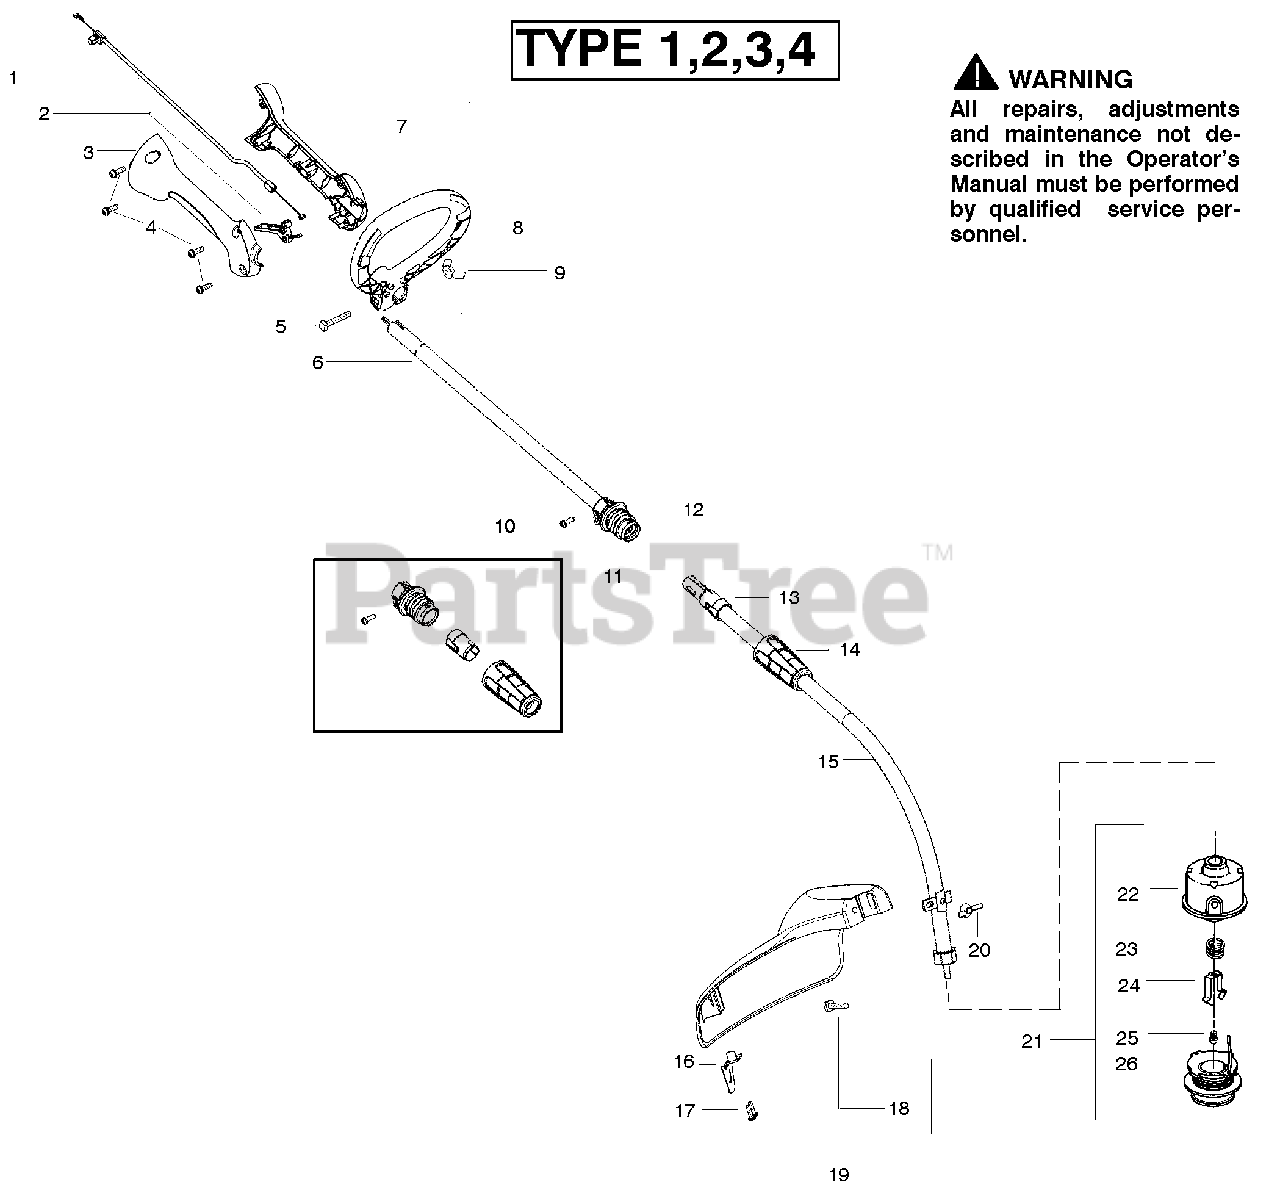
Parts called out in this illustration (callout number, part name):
1	Assy-Throttle Cable
3	Throttle Hsg. (Right)
4	Screw-Throttle Hsg.
6	Kit-Upper Shaft
7	Throttle Hsg. (Left)
8	Assy-Handle
9	Wingnut
10	Screw (10-14 x 5/8)
11	Kit-Coupler Shaft
15	Kit-Lower Shaft
16	Kit - Line Limiter
17	Screw-Line Limiter
19	Kit-Shield Assy
20	Wingnut
21	Accy-TNG IV Cutting Head
22	Assy-Hub
23	Spring-Compression
24	Clip-Retainer-Head
26	Accy- Spool w/Line
